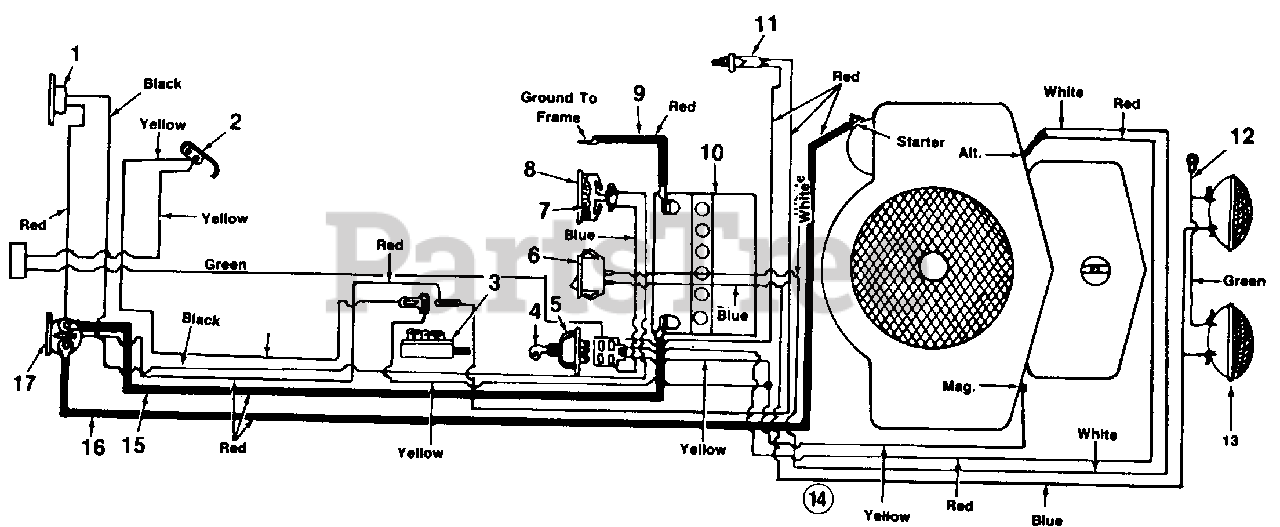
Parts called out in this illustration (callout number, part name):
1	Circuit Breaker
2	Spring Switch
3	Safety Switch Dpst.
4	Ignition Key
5	Ignition Switch
6	Headlight Switch
8	Ammeter
9	Grounding Wire 14.0" Lg.
10	32 Volt Battery
11	Safety Switch
12	Ground Wire
13	Headlight
14	Wire Harness
15	Electric Wire 27.0" Lg.
16	Electric Wire 32.5" Lg.
17	Solenoid
